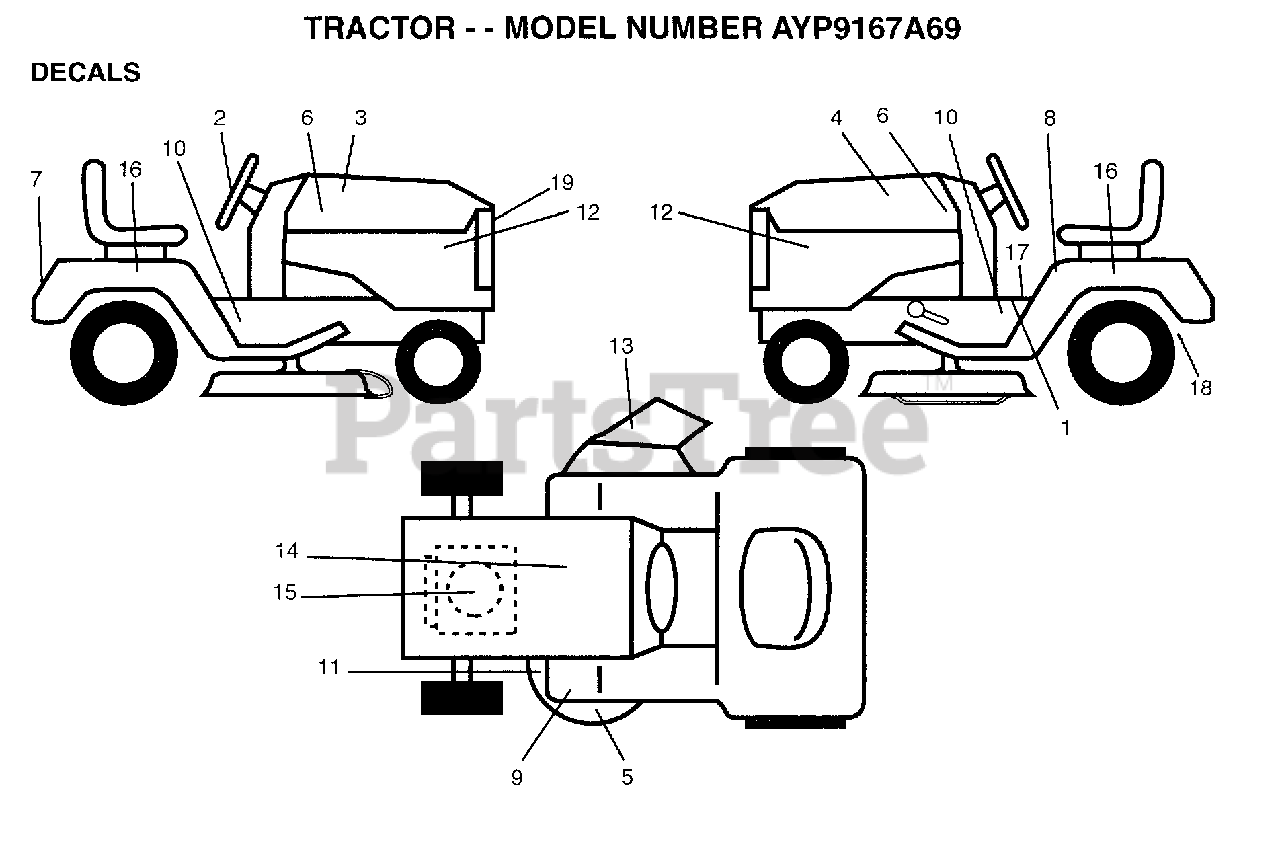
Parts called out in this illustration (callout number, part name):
2	DECAL STEER WHL
3	DECAL HOOD RH
4	DECAL HOOD LH
5	DECAL DECK WIZ +
6	NAMEPLATE.HD.WIZA
8	DECAL
10	"DECAL.CHASSIS.42"""
11	DECAL
12	DECAL.PNL.SIDE.VG
13	DECAL DECK MULCH
14	DECAL.BTRY.DANGER
15	DECAL.ENG.805720
16	DECAL.FENDER.WIZ
17	DECAL SADLE HYDRO
18	DECAL DRAWBAR LH
19	DECAL.LENS.WIZARD
